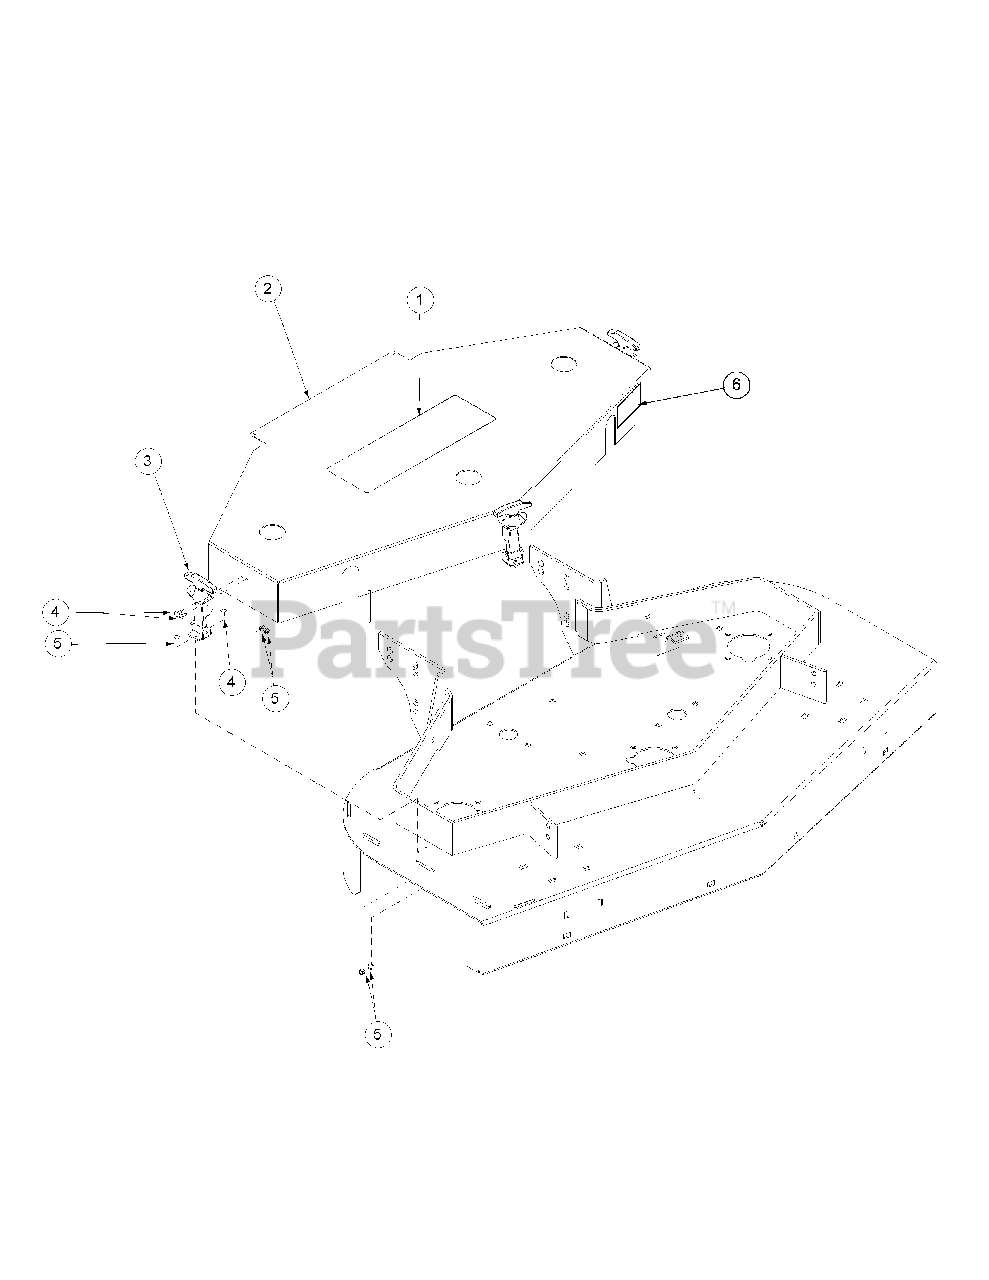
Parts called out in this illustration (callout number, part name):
1	Label Commercial Mower
2	Deck Cover 48"
3	Rubber Latch Hood
4	Machine Screw, 10-24 x 1/2
5	Lock Nut, Nylon Insert, #10-24
6	Label, G1548
